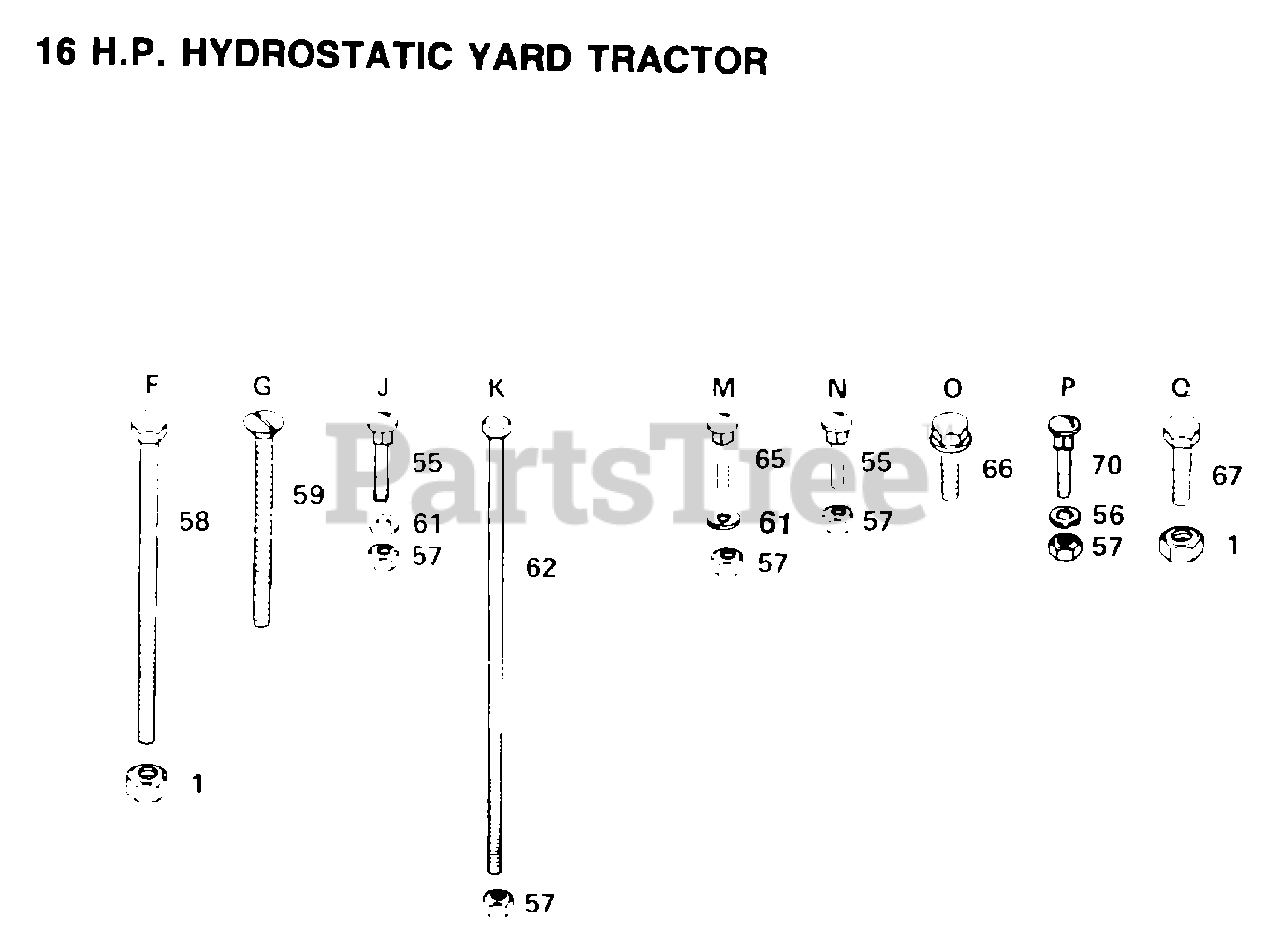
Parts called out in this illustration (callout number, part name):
55	BOLT
56	WASHER
58	BOLT - HEX 3/8 - 16 X 3
59	SCREW YT
61	WASHER M
62	BOLT
65	BOLT
66	SCREW
67	BOLT
